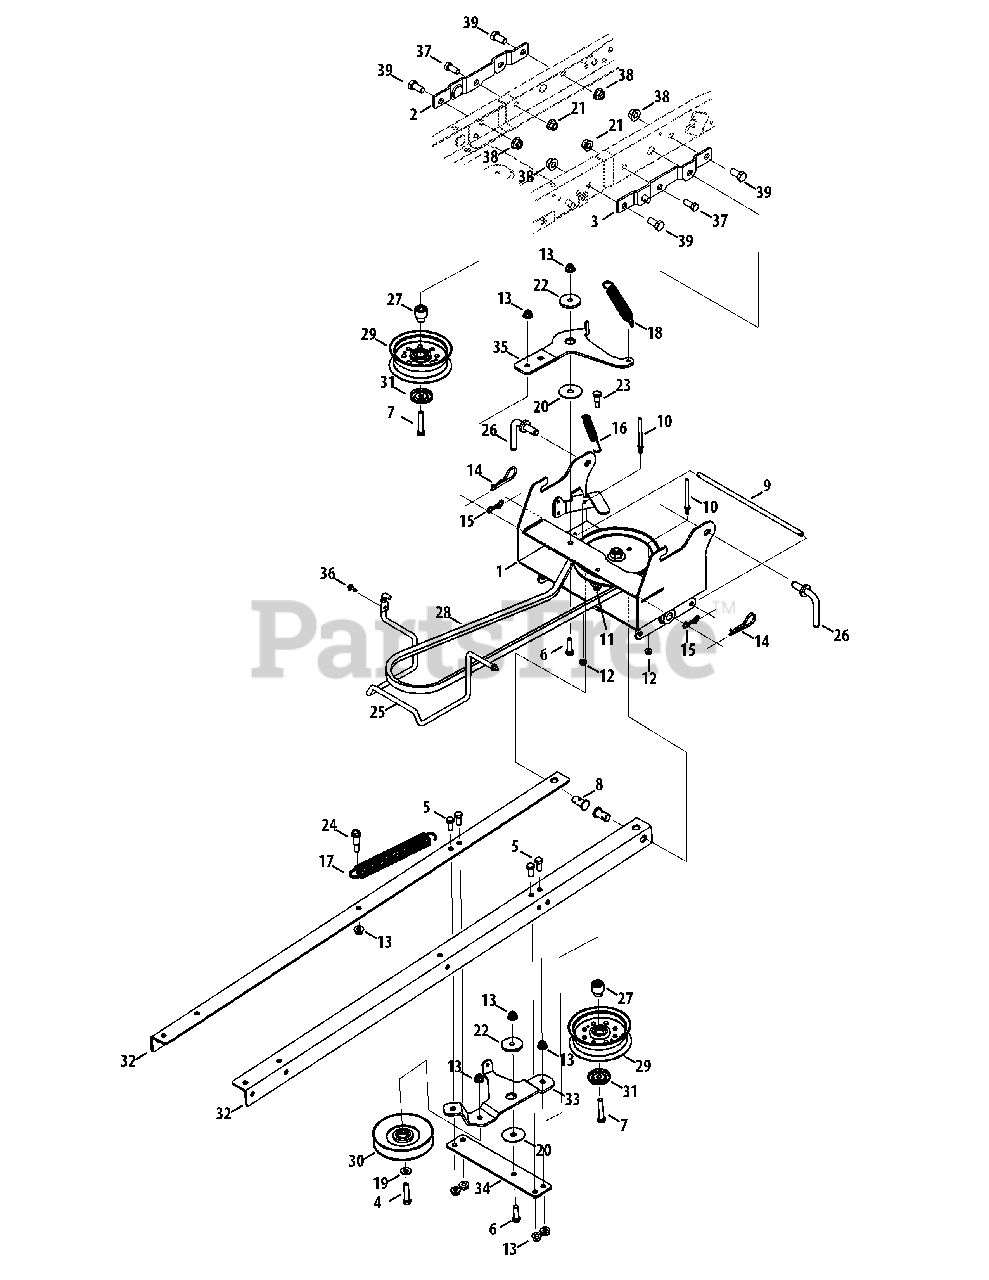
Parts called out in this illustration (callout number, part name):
1	Spindle Housing
1	Spindle Hanger Bracket
1	Hex Washer Screw, 5/16-18 x .750
2	Bracket Assembly, Hanger, Right
3	Bracket Assembly, Hanger, Left
4	Hex Screw, 3/8-16, 1.75, Gr5, Std
5	Hex Screw, 3/8-16, .880, Gr5, Std
6	Hex Screw, 3/8-16, 1.25, Gr5, Std
7	Hex Screw, 3/8-16, 2.00, Gr5, Std
8	Pin, Clevis, .62 Dia.
9	Shaft, .375Od x 12.3450 Lg
10	Keeper, Belt, .25 Dia x 3.0
11	Nut, Flange Lock, 5/16-18, Grf, Nylon
12	Nut, Flange Lock, 1/4-20, Grf, Nylon
13	Nut, Flange Lock, 3/8-16, Grf, Nylon
14	Pin, Cotter, Int, .148 x 3.00
15	Pin, Cotter, Bow-Tie 91
16	Spring, Extension, .53 Dia x 4.75 Lg
17	Spring, Extension, 1.25 OD x 8.5 Lg.
18	Spring, Extension, 6.45 Lg
19	Washer, Flat, .385 x .870 x .092
20	Washer, Thrust, .445 x 1.92 x .060
21	Nut, Flange Lock, 1/2-13, Grf, Nylon
22	Spacer, Shoulder, .8840 x .190
23	Screw, Shoulder, .437 Dia. x .54
24	Bolt, Shoulder, .50 x .925, 3/8-16
25	Rod, Keeper, Engine Pulley
26	Rod, Lock, .500
27	Spacer, Shoulder, Idler Pivot
28	Belt, V-type, Bsec, 68.2
29	Pulley, Idler, 4.50" Dia
30	Pulley, Idler, 5.06 Dia
31	Cap, Pulley, Hd
32	Bracket, Link
33	Bracket, Idler, Pivot
36	Screw, M6-1 x .625"
37	Hex Screw, 7/16-14, 1.00, Gr5, Std
38	Nut, Flange Lock, 7/16-14
39	Hex Screw, 1/2-13, 1.00, Gr5, Std
